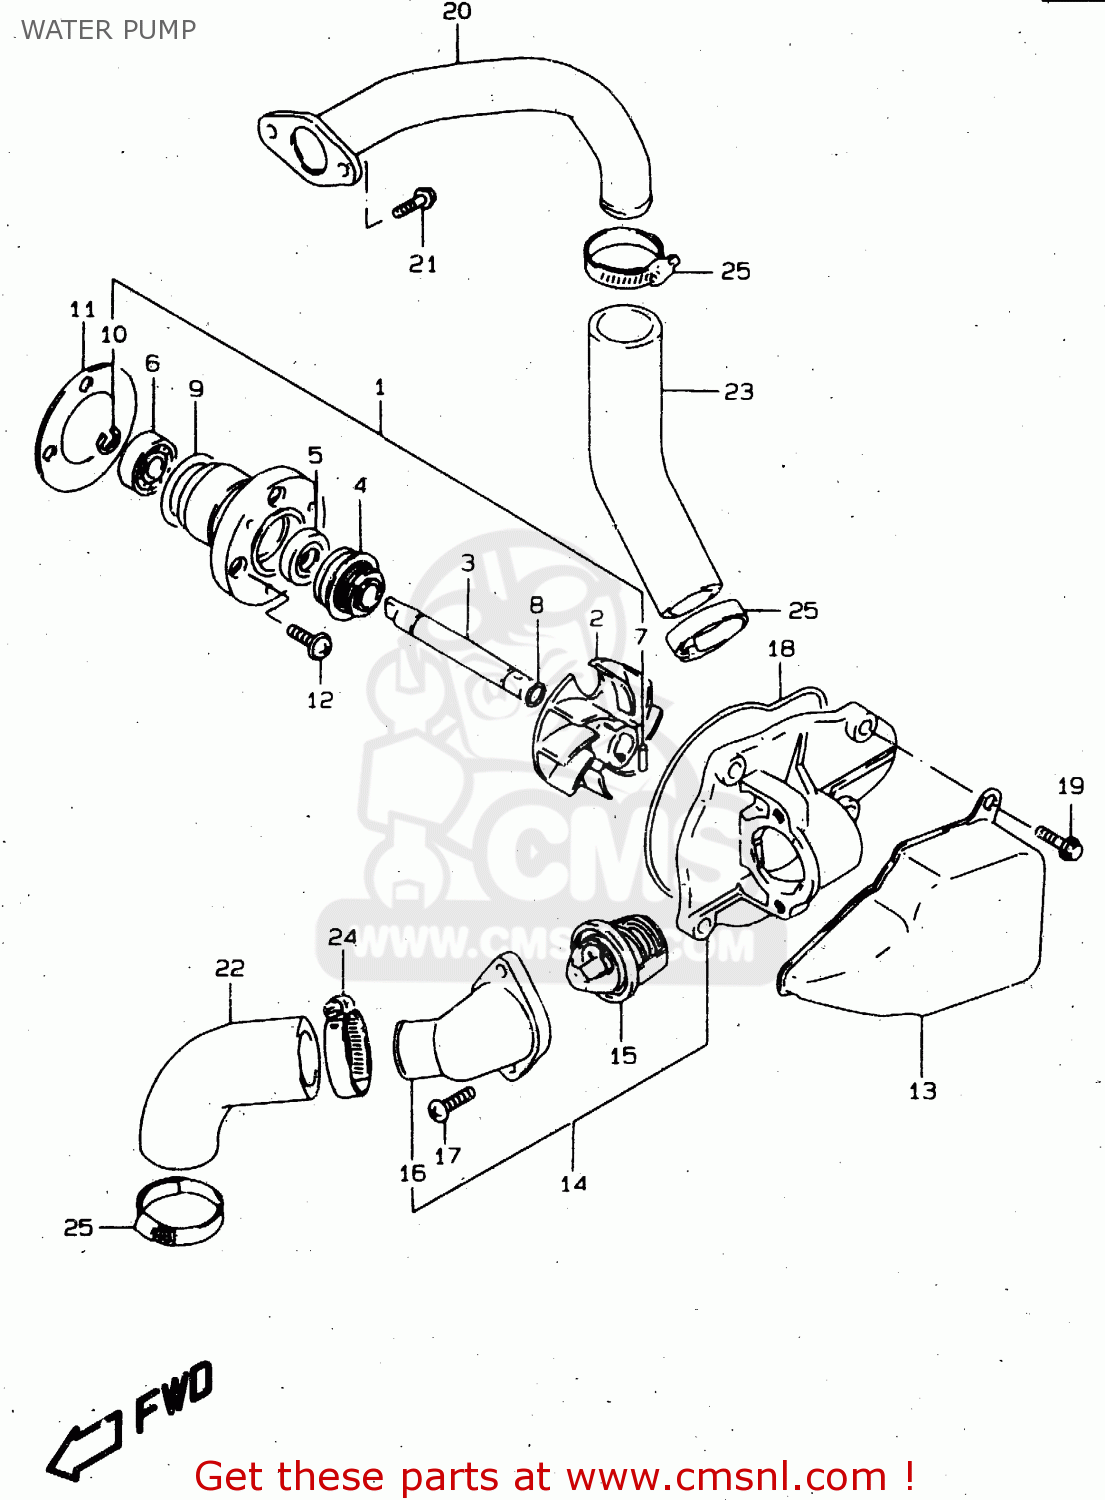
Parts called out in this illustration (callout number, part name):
1	PUMP ASSEMBLY,WATER
2	IMPELLER
3	SHAFT
4	SEAL,MECHANICAL
5	SEAL,OIL(10X21X5)
6	BEARING(10X22X6)
7	PIN
8	O RING
9	O RING
10	E RING
11	GASKET,WATER PUMP (NAS)
12	SCREW
13	COVER,WATER PUMP
14	CASE ASSY,WATER PUMP
15	THERMOSTAT,WATER
16	CONNECTOR
17	SCREW
18	O RING,WATER PUMP CAP
19	BOLT
20	PIPE,CYLINDER INLET
21	BOLT
22	HOSE,WATER PUMP IN
23	HOSE,WATER PUMP OUTLET
24	CLAMP
25	CLAMP
